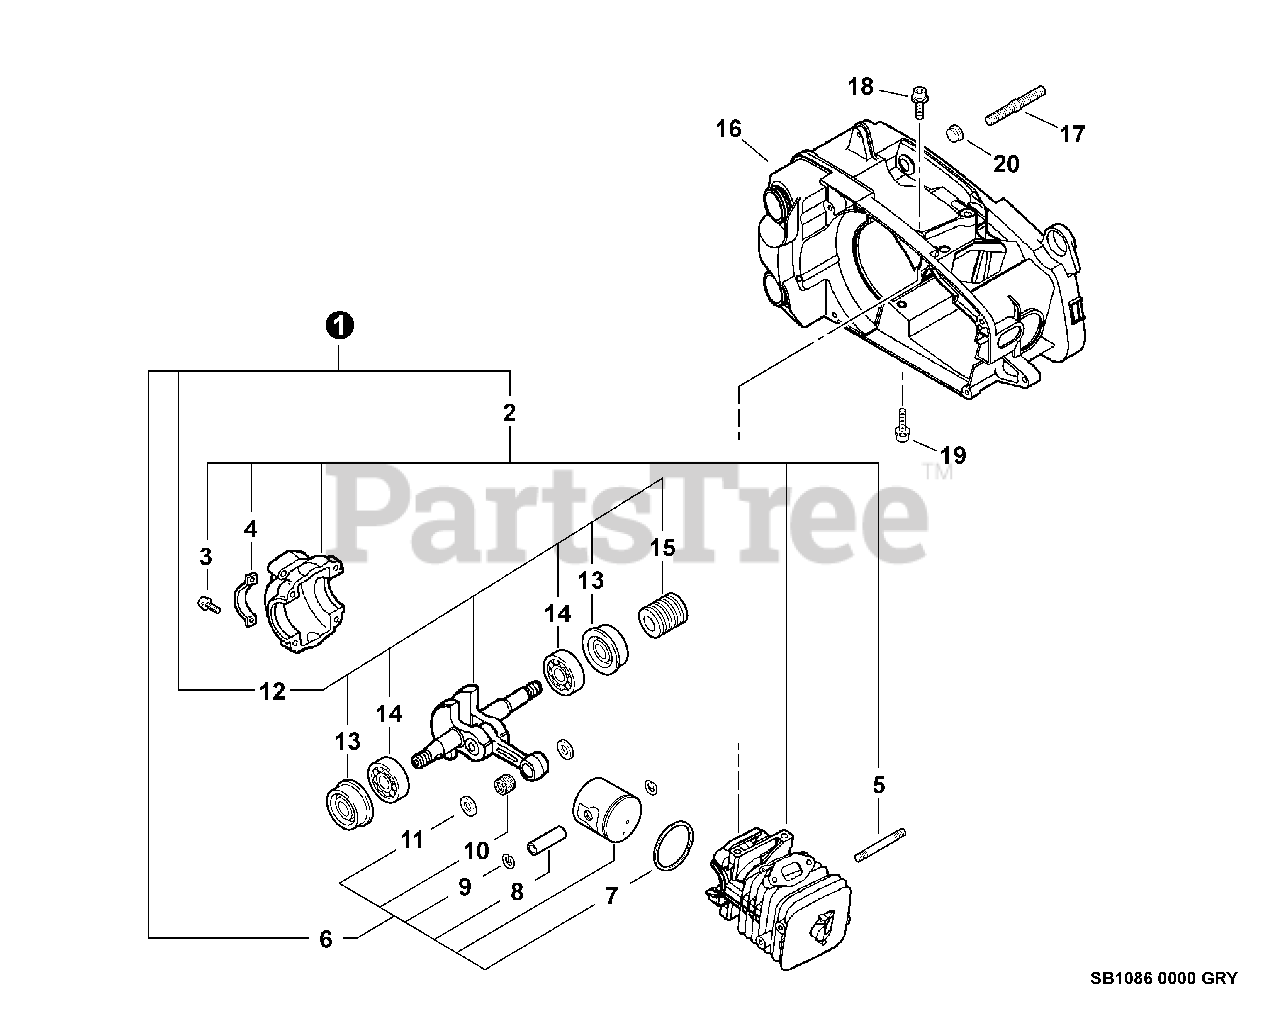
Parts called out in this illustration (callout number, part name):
1	SHORT BLOCK
2	CRANKCASE KIT
3	SCREW 5×25
4	BRACKET, CRANKCASE
5	BOLT, STUD
6	PISTON KIT
7	RING, PISTON
8	PIN, PISTON
9	RING, SNAP
10	BEARING, NEEDLE 8
11	WASHER, THRUST
12	CRANKSHAFT ASSY
13	SEAL, OIL 12
14	BEARING, BALL - 6201 C3
15	GEAR, WORM
16	COVER ASSY, ENGINE - GRAY
17	BOLT, STUD 6
18	BOLT 5×20
19	BOLT 5×30
